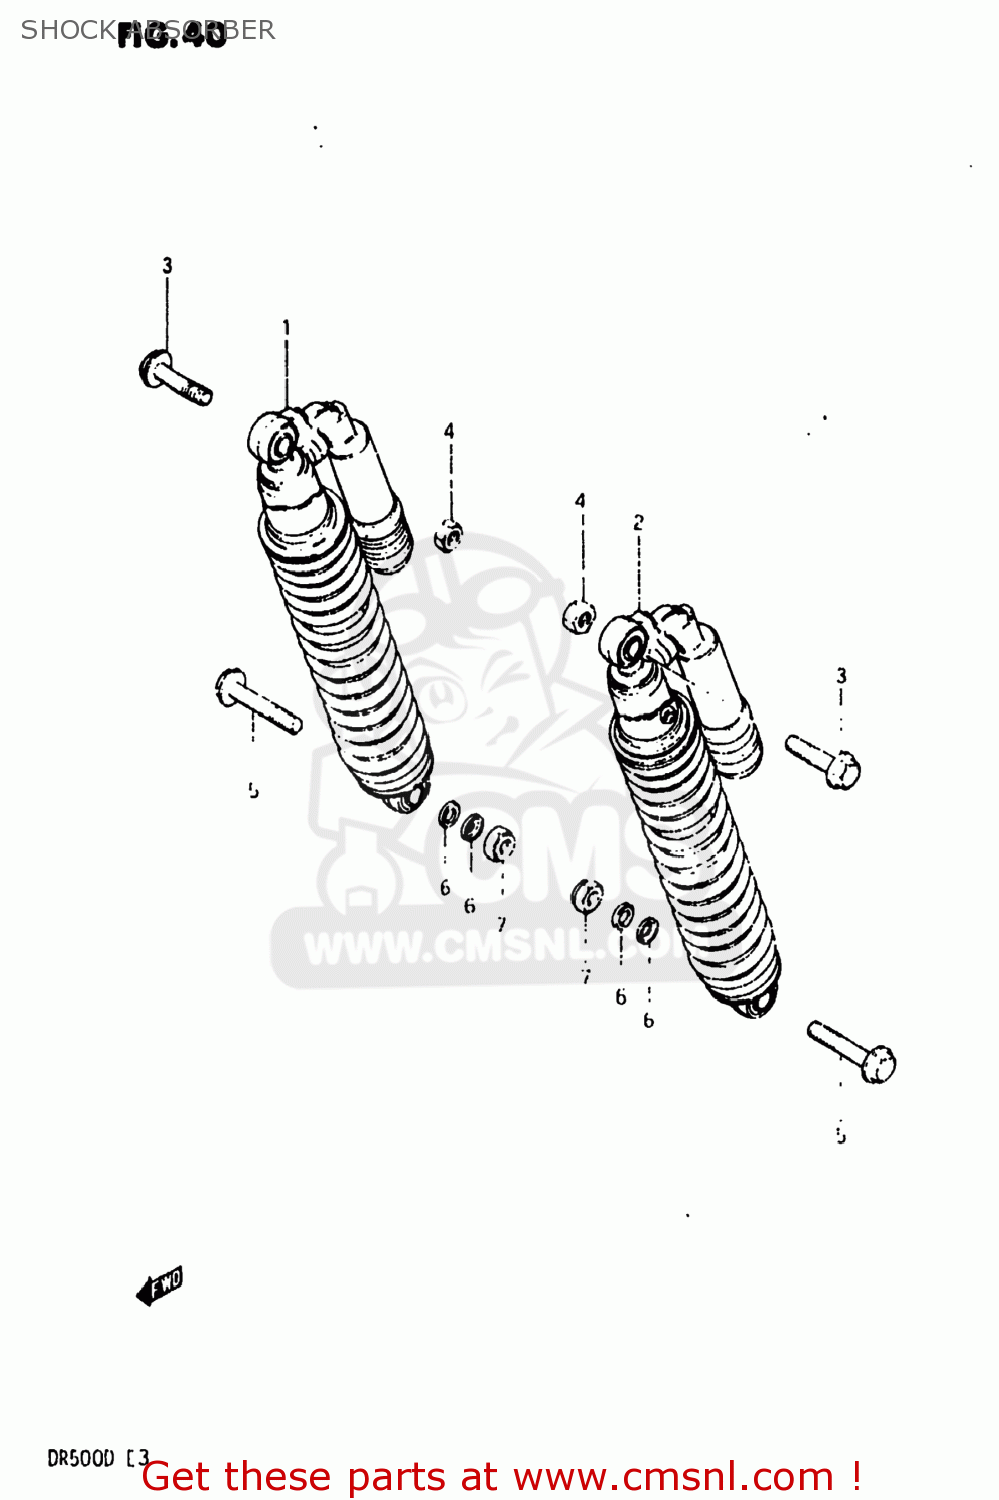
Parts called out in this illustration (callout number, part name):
1	ABSORBER ASSEMBLY,REAR SHOCK
2	ABSORBER ASSEMBLY,REAR SHOCK
3	BOLT(10X40)
4	NUT
5	BOLT
6	WASHER,REAR SHOCK ABSORBER
7	NUT
